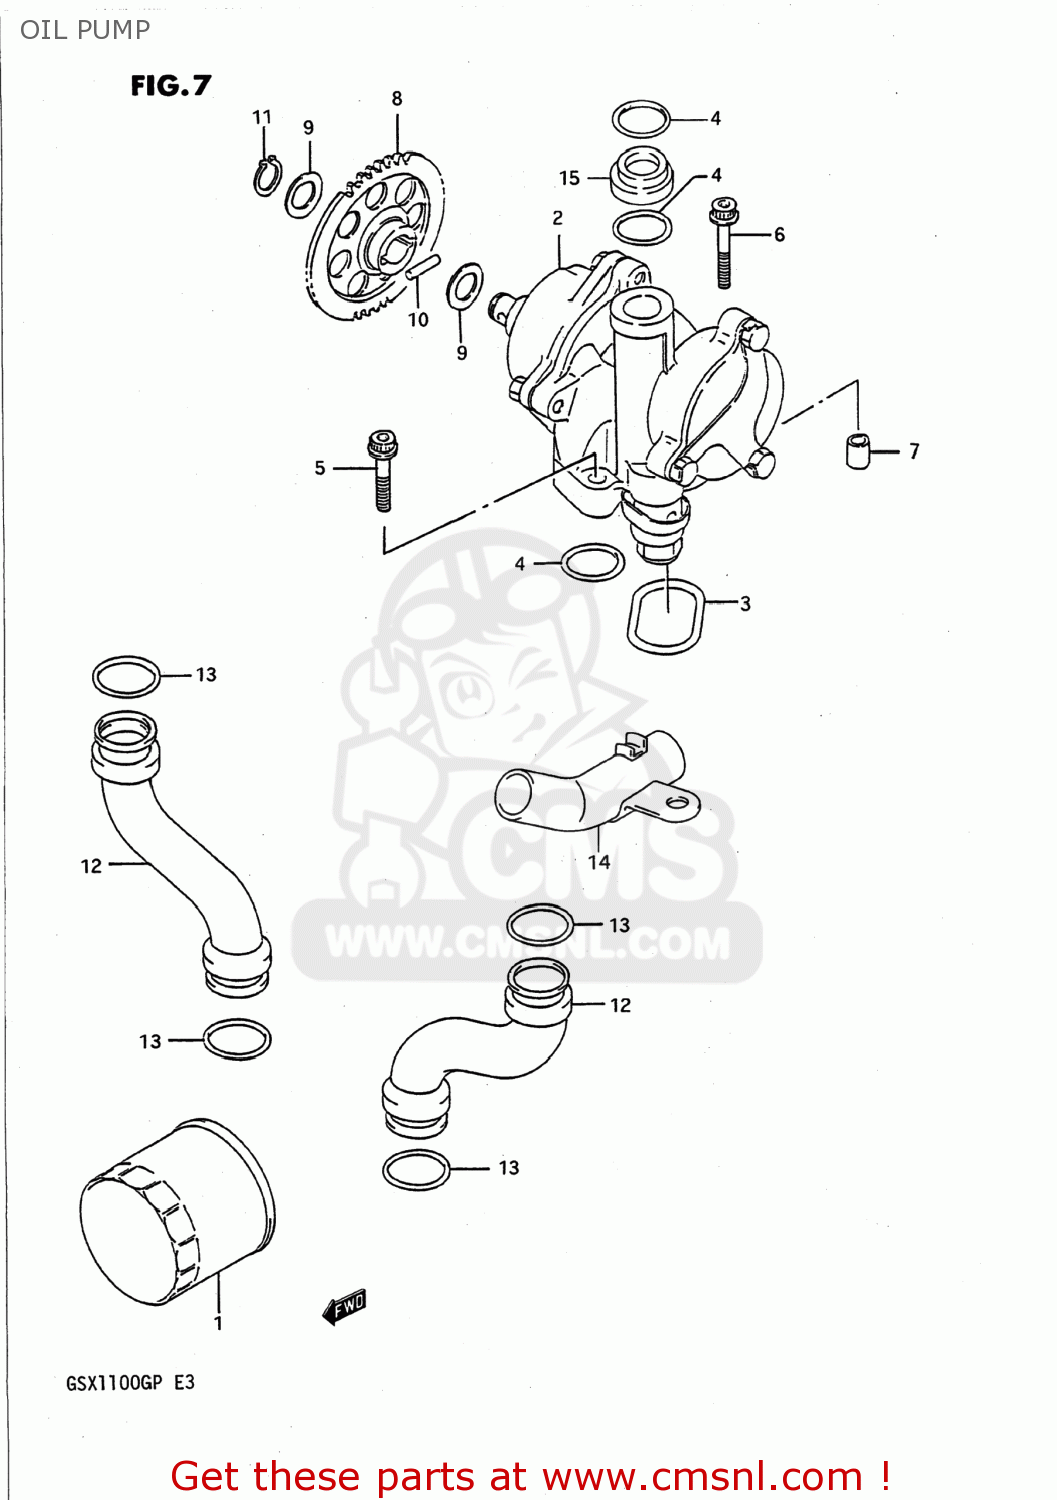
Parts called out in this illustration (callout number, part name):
1	FILTER ASSEMBLY,ENGINE OIL
2	PUMP ASSEMBLY,OIL
3	O RING,OIL PUMP
4	O RING(D:3.2,ID:17.8)
5	BOLT
6	BOLT
7	PIN
8	GEAR,OIL PUMP DRIVEN
9	SHIM
10	PIN(5X18)
11	CIRCLIP,12 MM
12	PIPE,OIL OUTLET
13	O RING(D:3.7,ID:21.7)
14	PIPE COMP,OIL OUTLET
15	SPACER,OIL PUMP
